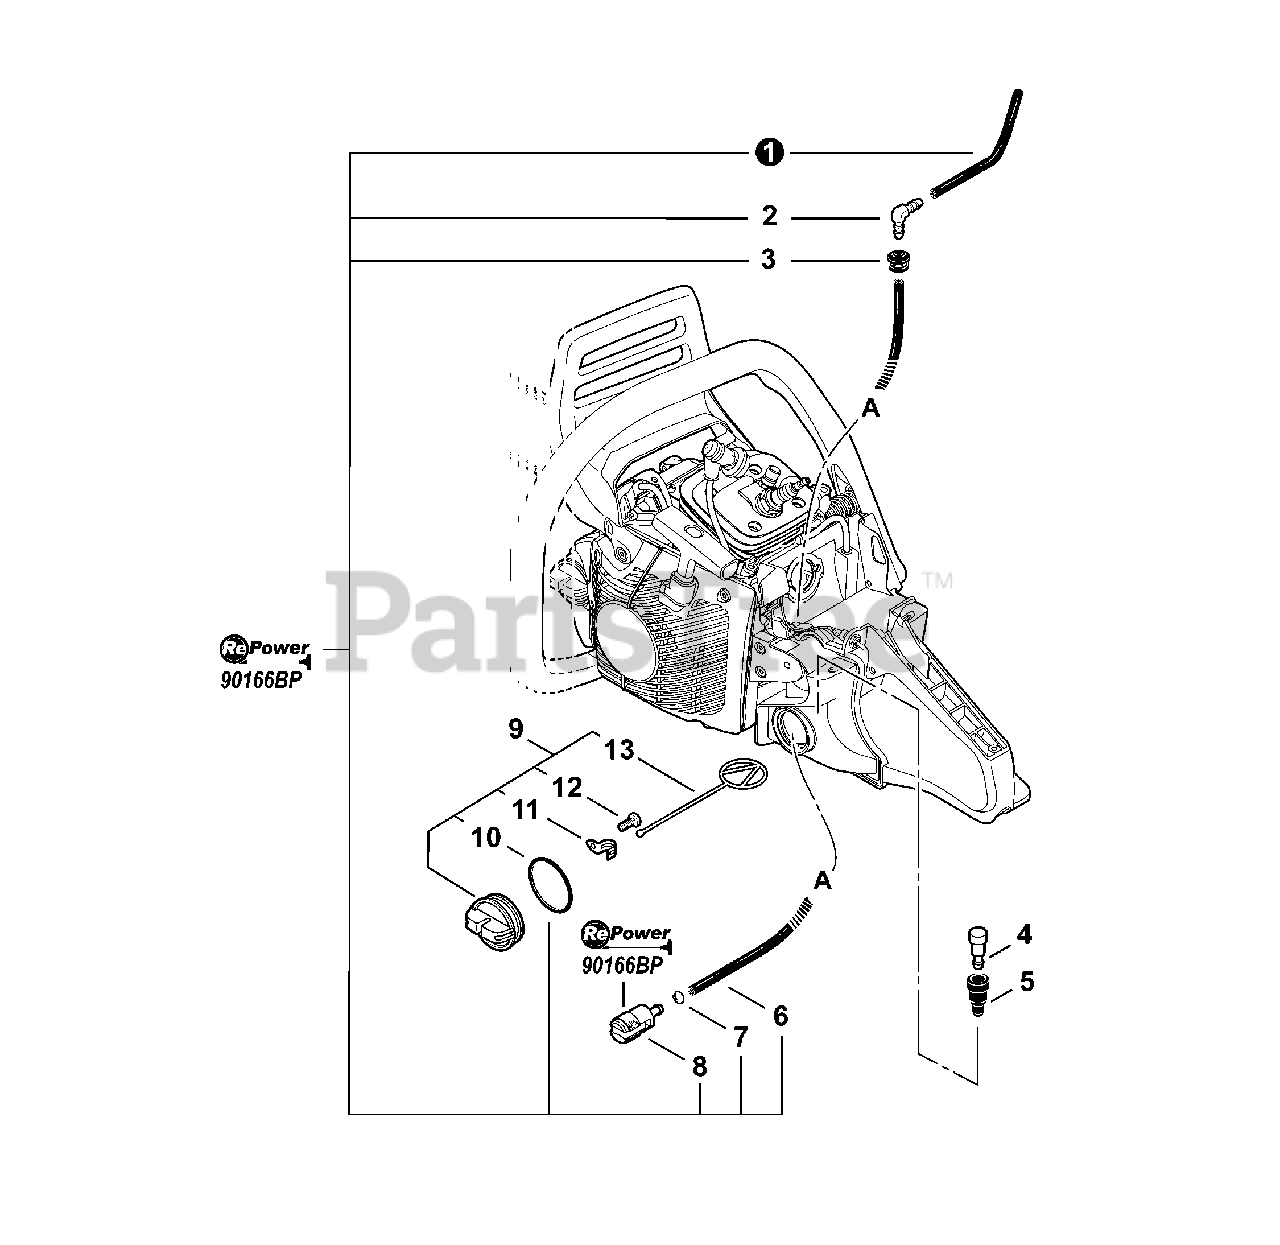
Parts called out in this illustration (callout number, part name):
1	PIPE - 3×6×135 -- BLACK
2	CONNECTOR, FUEL PIPE
3	GROMMET
4	VENT, FUEL TANK
5	COVER, VENT
6	PIPE - 3×5×120 -- BLACK
7	CLIP - 6
8	FILTER, FUEL
9	CAP ASY
11	RETAINER, CONNECTOR
12	SCREW - 3×8
13	CONNECTOR, CAP
